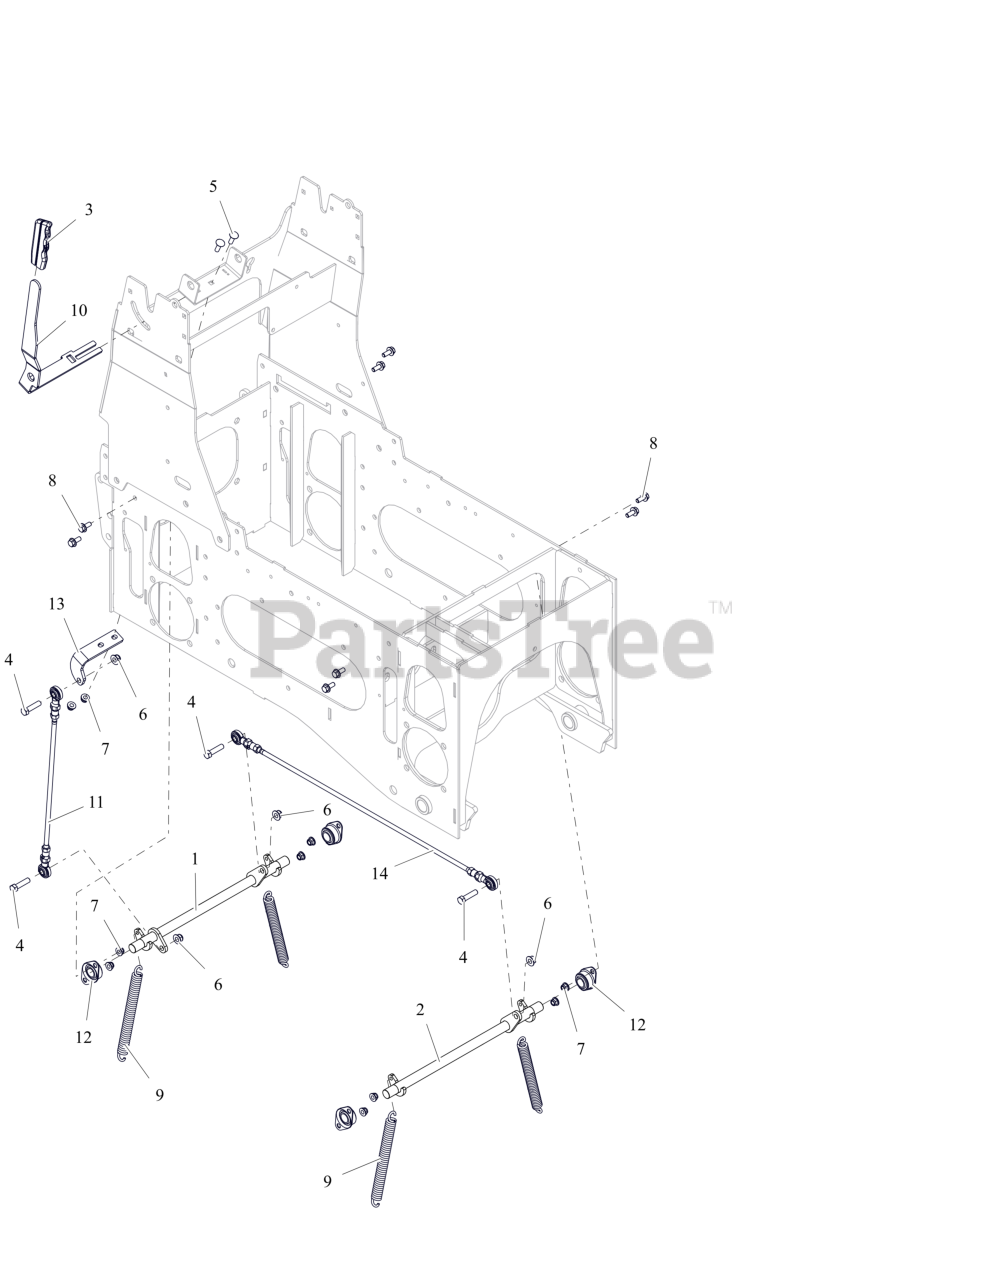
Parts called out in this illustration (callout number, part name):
1	WLDMT- BRAKE SHAFT-REAR
2	WLDMT- BRAKE SHAFT-FRONT
3	GRIP, PARKING BRAKE (GREY)
4	BLT, HEX .38-16X1.50 G5 ZCC
5	BLT,RHSN .31-18X1.00 G5 ZCC
6	NUT,NYL-FLG .38-16 GF ZCC
7	NUT,LK-NYL-FLG .31-18 G5ZC120
8	BLT- SERHFWH .312-18X.75 ZCC
9	SPRG-EXT HOOKS 90DEG-SS-7.38"
10	PLATE, BRAKE LEVER
11	LINKAGE- UPPER BRAKE- 17-9/16"
12	ASM- SIDE FLANGE BRG. 3/4"
13	BRKT- OVER CENTER
14	LINKAGE- LOWER BRAKE-28"
